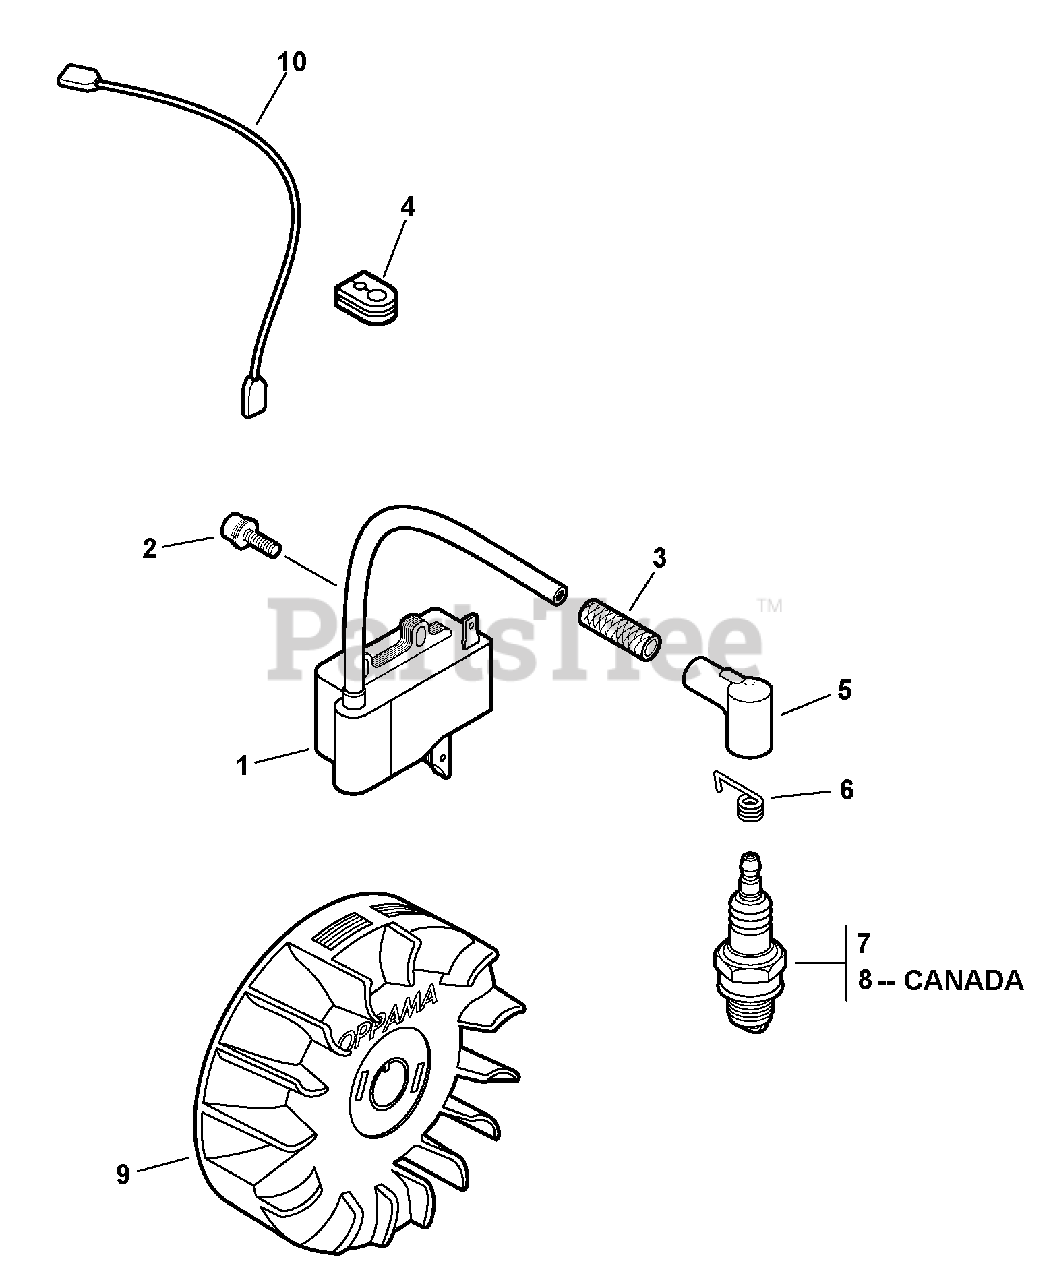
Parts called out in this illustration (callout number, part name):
1	COIL, IGNITION
2	BOLT 4×20
3	TUBE, INSULATOR
5	CAP, SPARK PLUG
6	TERMINAL, SPARK PLUG
7	SPARK PLUG - BPM8Y
8	SPARK PLUG - BPMR8Y
9	FLYWHEEL
